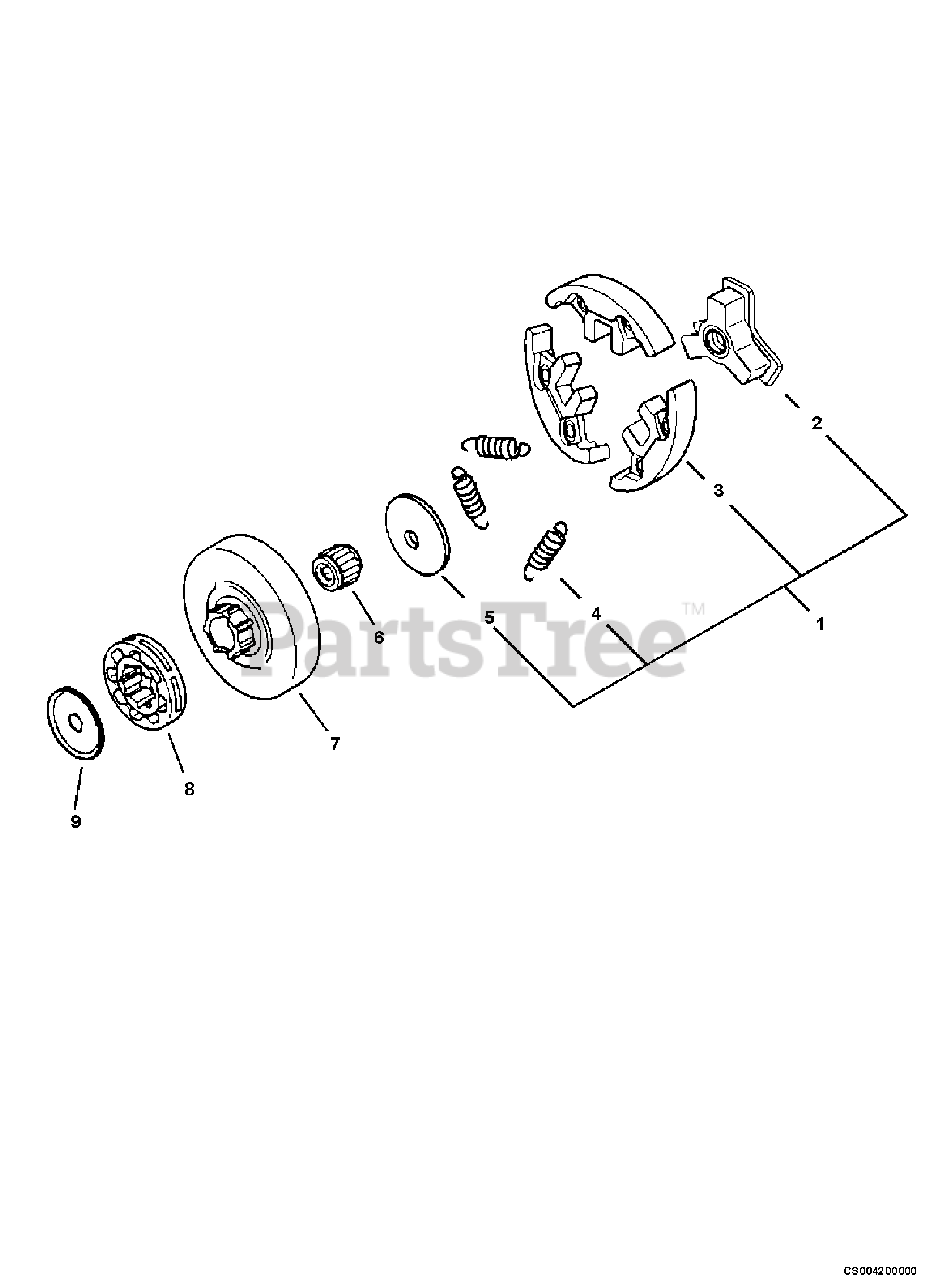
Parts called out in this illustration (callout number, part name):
1	CLUTCH ASSY
2	HUB, CLUTCH
3	SHOE SET, CLUTCH (3PCS)
4	SPRING, TENSION
5	PLATE, CLUTCH
6	BEARING, NEEDLE
7	DRUM, CLUTCH
8	SPROCKET, 0.325 RIM
9	PLATE, CLUTCH
